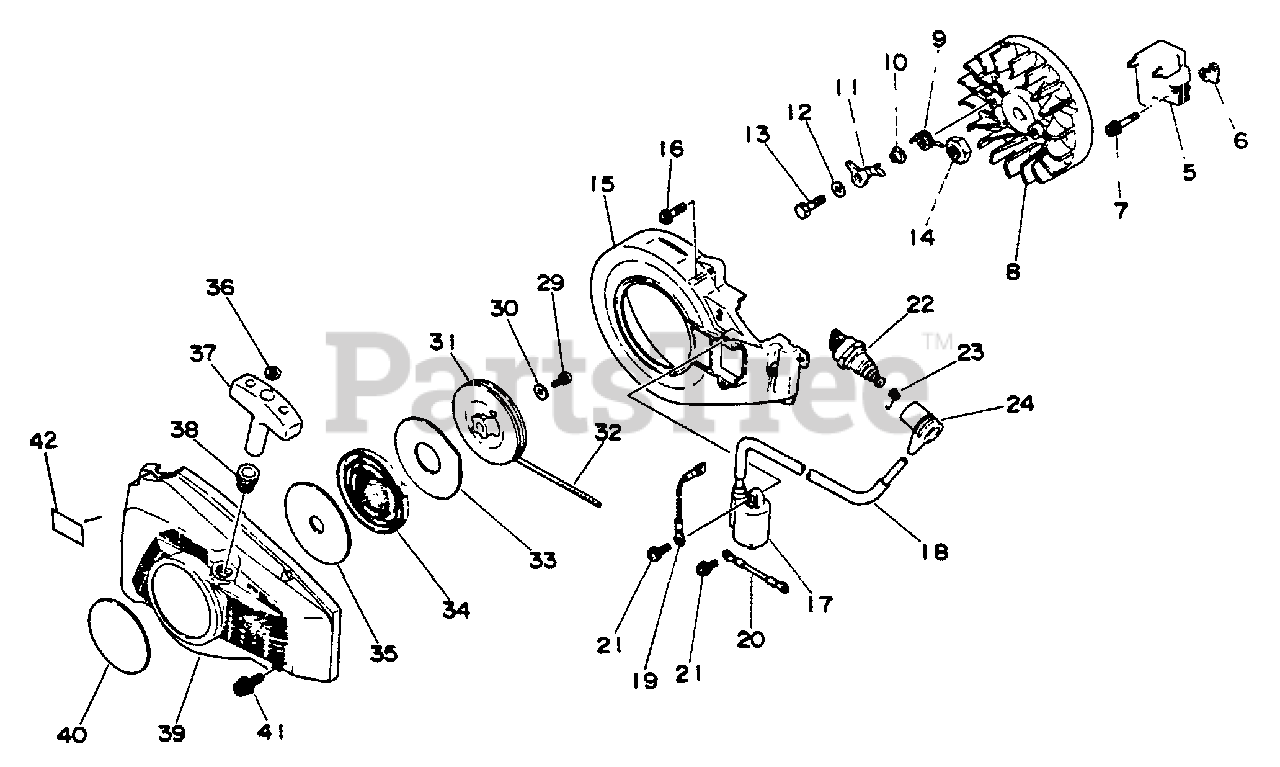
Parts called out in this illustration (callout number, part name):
5	COIL, IGNITION
7	SCREW - 4X22
8	FLYWHEEL
9	SPRING, RETURN
10	SPACER
11	PAWL, STARTER
12	WASHER - 5
13	BOLT - 5X20
15	SHIELD, FAN
16	SCREW - 4X20
17	COIL, IGNITION
18	TUBE
19	LEAD
20	LEAD - GROUND
21	SCREW - 4X14
22	SPARK PLUG -- CJ-7Y
23	TERMINAL, SPARK PLUG CAP
24	CAP, SPARK PLUG
29	SCREW - 5X10
30	WASHER - 5
31	REEL, ROPE
32	ROPE, STARTER - 4X950
33	PLATE, STARTER
34	SPRING, REWIND
35	PLATE, STARTER
36	RING, RETAINING
37	GRIP, STARTER
38	GUIDE, ROPE
39	CASE, STARTER
40	LABEL - ECHO
41	SCREW - 5X20
42	LABEL - NOISE
